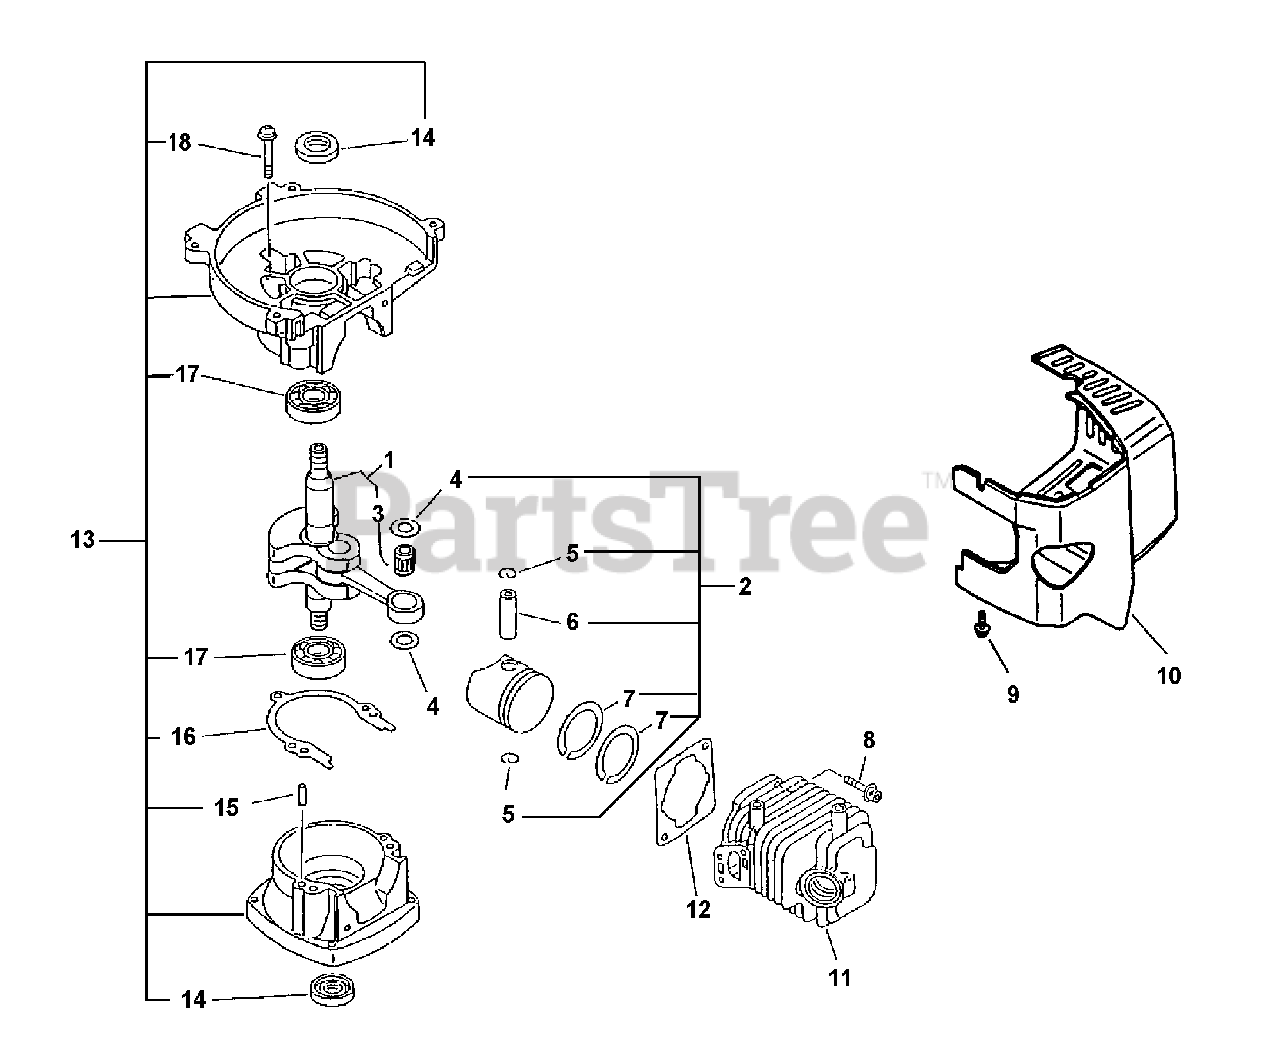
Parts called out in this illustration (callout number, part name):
1	CRANKSHAFT ASSY
2	PISTON KIT
3	BEARING, NEEDLE
4	WASHER, THRUST
5	RING, SNAP
6	PIN, PISTON 8
7	RING, PISTON
8	BOLT 5×22
9	BOLT 4×20
10	COVER, ENGINE
11	CYLINDER
12	GASKET, CYLINDER
13	CRANKCASE SET
14	SEAL, OIL 12
15	PIN, LOCATING 4
16	GASKET, CRANKCASE
17	BEARING, BALL - 6201 C3
18	BOLT 5×28
